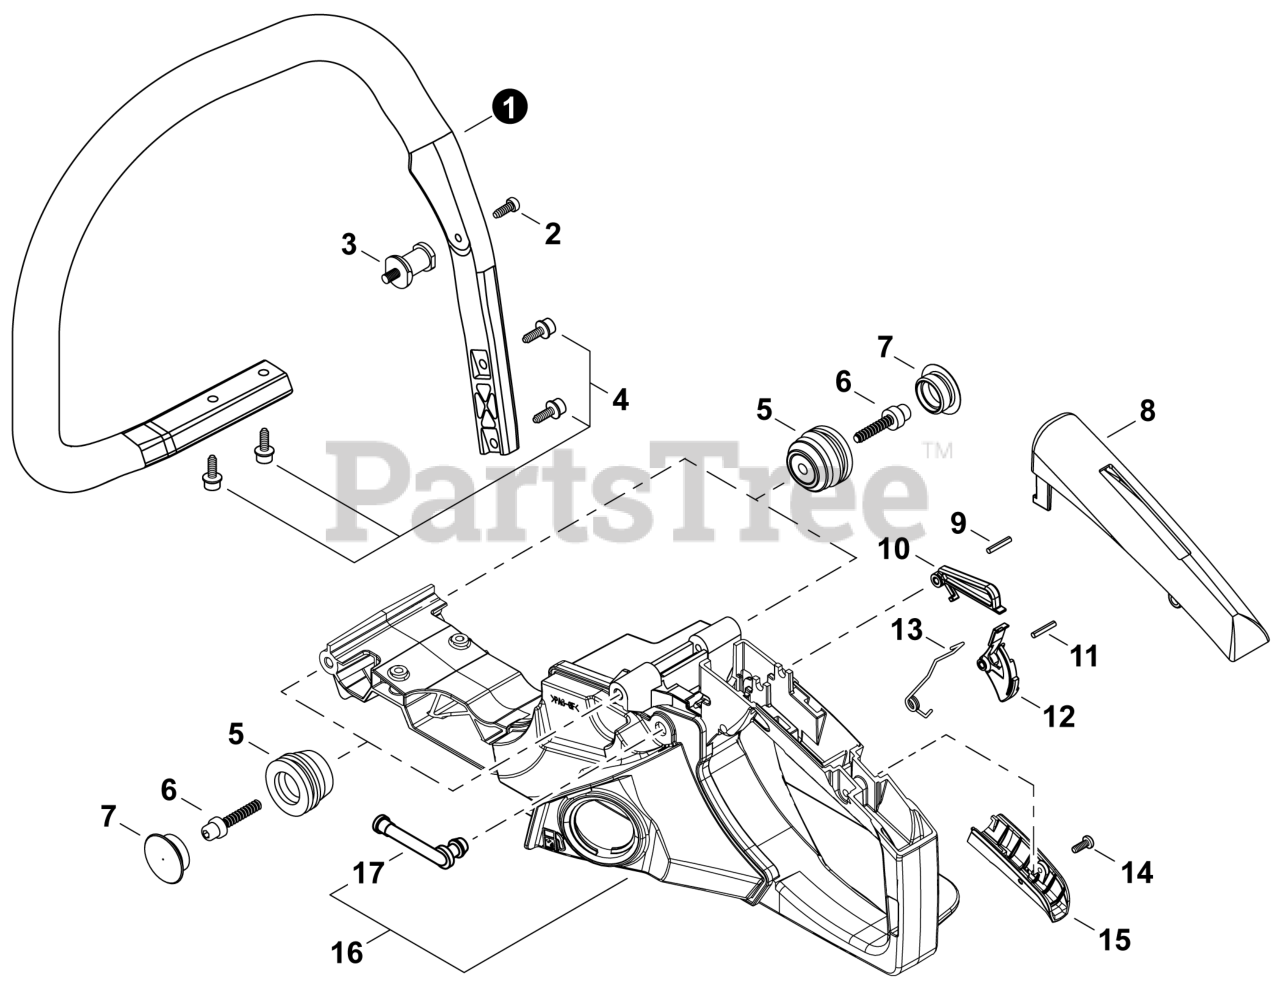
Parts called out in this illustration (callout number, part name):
1	HANDLE, FRONT
2	BOLT M4x14
3	CUSHION 5
4	BOLT 5x20
5	CUSHION
7	CAP, CUSHION
8	COVER, HANDLE
9	PIN, SPRING 4x22 MM
10	LOCKOUT, THROTTLE
11	PIN, SPRING 4x25 MM
12	TRIGGER, THROTTLE
13	SPRING, THROTTLE RETURN
14	SCREW 4x25
15	GRIP, LOWER
16	HANDLE ASSY, REAR
17	PIPE, FUEL VENT 2x5x43
